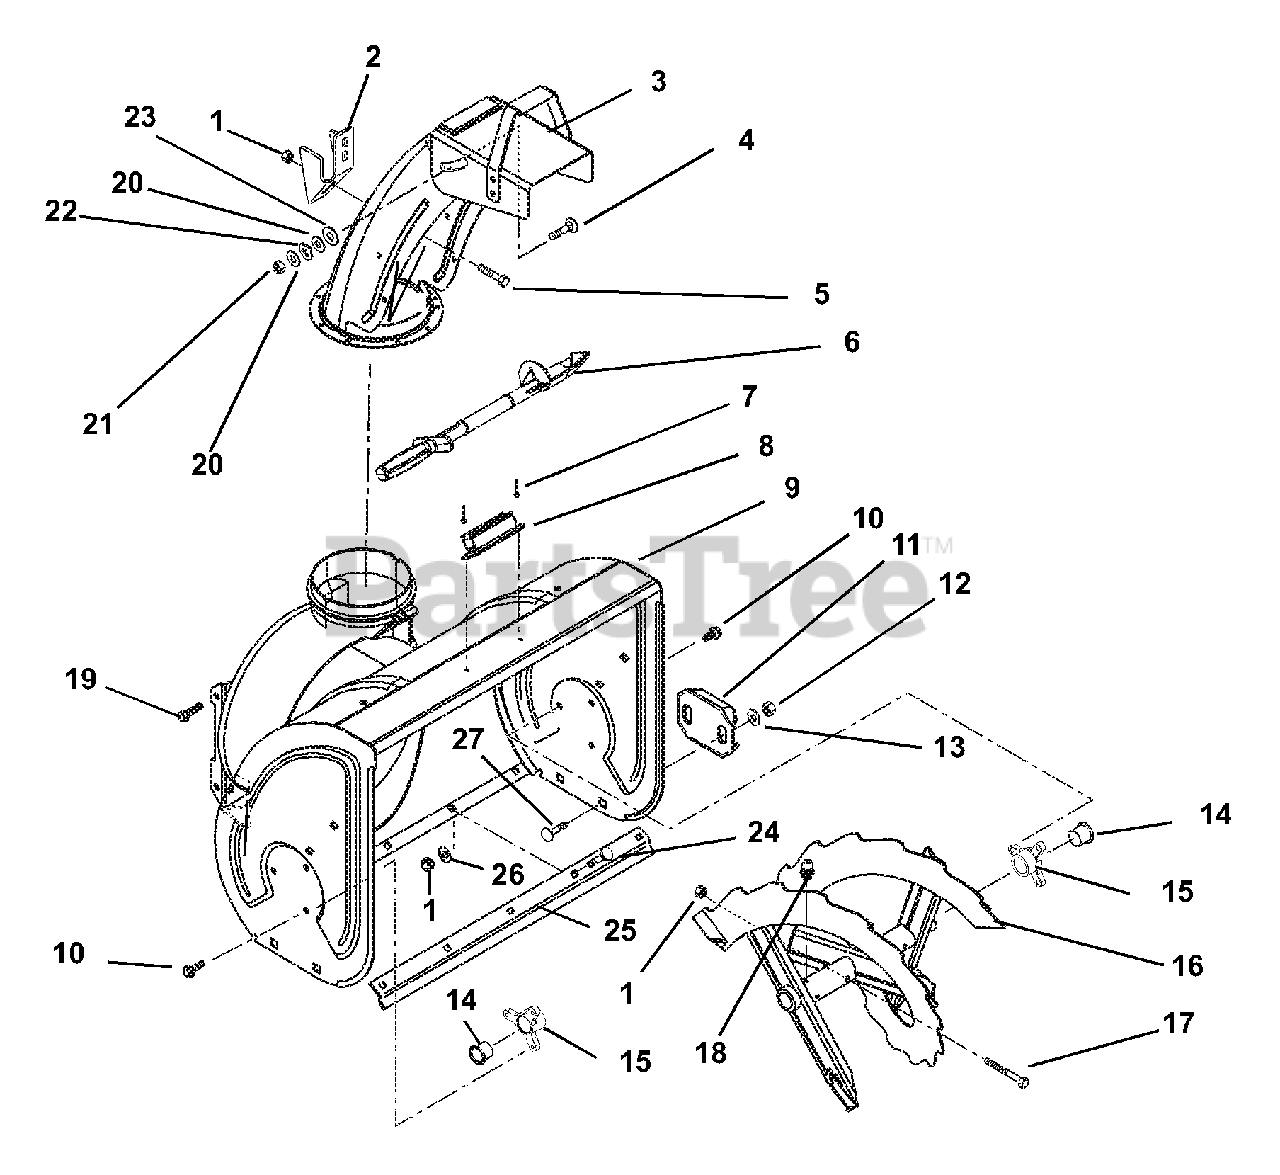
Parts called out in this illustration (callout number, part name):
1	@NUT-LK-CTR .25-20 YWZC
2	CHUTE STRAP
3	CHUTE, DISCHARGE W/CAP & DECAL
4	@BLT-RHDSSQNK .31-18X.75 G5YZ
5	@BLT-HEX .25-20X.50 GR5 YWZC
6	DEVICE, SNOW CLEAN OUT
7	RVT-POP .187X.45 DOME SS FBF64
8	MOUNT, SNOW CLEAN OUT
9	BLOWER HOUSING, 24"
10	@SCR-TAP .25-20X.50 HWH TR YWZ
11	SKID SHOE, REVERSIBLE - ORANGE
12	@NUT-LK-CTR .38-16 YWZC
13	@WSHR-FL-STL.38X.875X.083 YWZC
14	BSHG-FLG, SPLIT NYLINER .75"ID
15	BUSHING, RAKE SHAFT .75"
16	RAKE, 24" RH, BLK SERR W/ZERK
17	SHEAR BOLT WITH NUT
18	ZERK,FITTING .25X.125 DRIVE IN
19	@SCR-TAP .38-16X.50 HWH TR YWZ
20	@WSHR-FL-STL.344X.688X.065YWZC
21	@NUT-LK-CTR .31-18 YWZC
22	WAVE WASHER .390X.655X.110
23	WSHR-PLASTIC .390X.875X.062
24	BLT-RDHDSQSHNK.25-20X.50 YWZC
25	SCRAPER BLADE
26	@WSHR-FL-STL.281X.62X.065 YWZC
27	BLT-RHHDSQSHNK .38-16X.75 G2YZ
